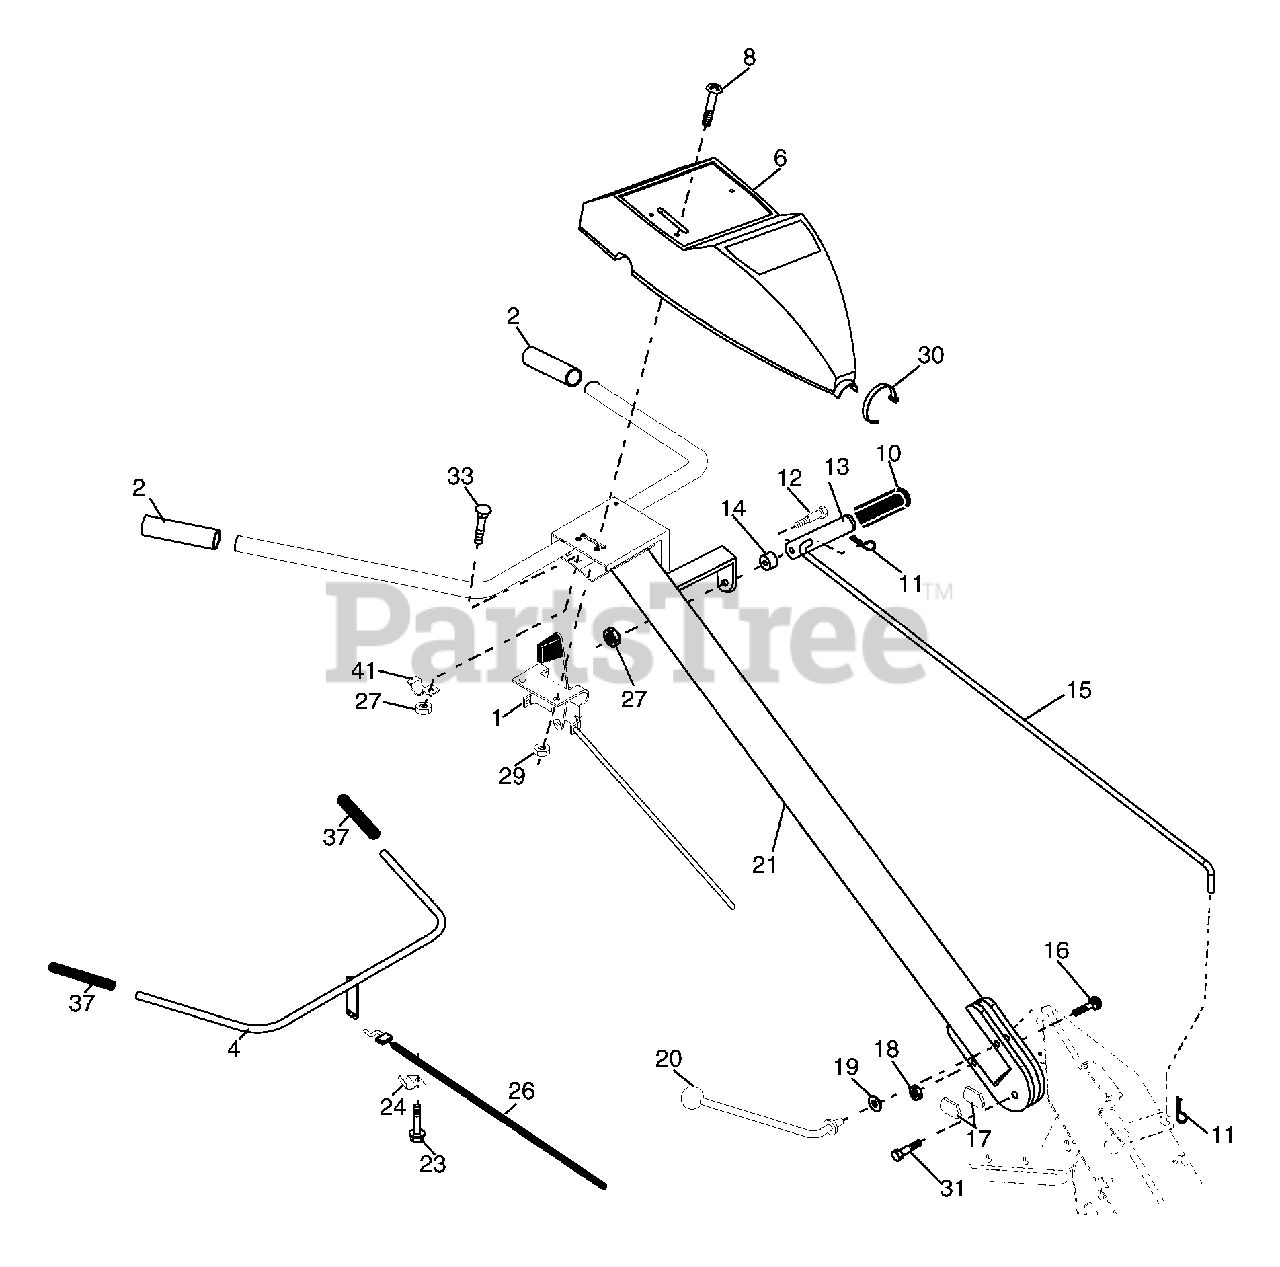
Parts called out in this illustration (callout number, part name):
1	Control, Throttle
2	Grip, Handle
4	Bar Assembly, Control
6	Panel, Control
8	Screw, Phd. #10-24
10	Grip, Handle
11	Clip, Hairpin
12	Bolt, Shoulder
13	Handle, Shift
14	Grommet, Rubber
15	Rod, Shift
16	Bolt, Carriage 3/8-16 x 1 Gr. 5
17	Lock, Handle
18	Nut, Crownlock 3/8-16 unc
19	Washer 13/32 x 1 x 11 Ga.
20	Lever, Lock, Handle
23	Screw, Hex Washer Hd. Slotted #10-24 x 1/2
24	Clip
26	Cable, Clutch
27	Nut Hex Flange 1/4-20 unc
29	Nut, Keps #10-24 unc
30	Tie, Cable
31	Bolt, Pivot
33	Bolt, Carriage 1/4-20 unc x 1/2
37	Grip, Bar, Control
41	Clamp, Bar, Control
